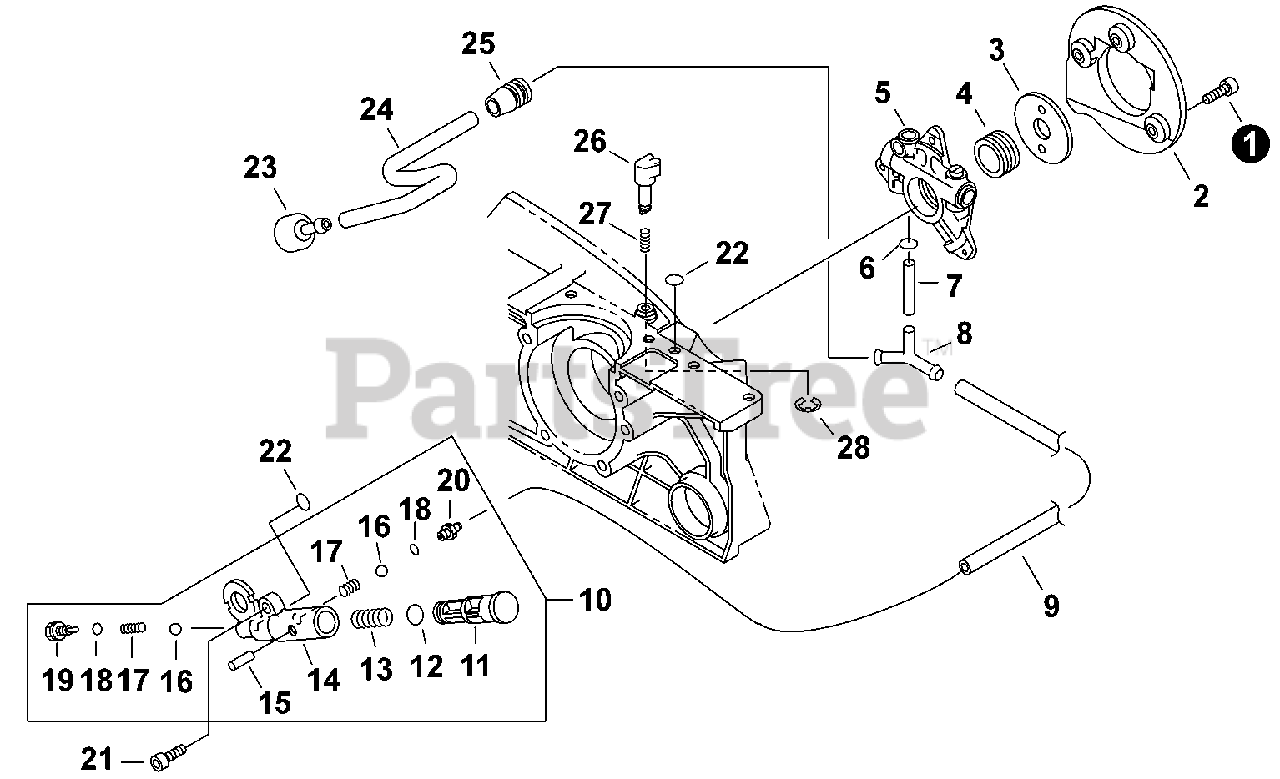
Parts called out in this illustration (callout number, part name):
1	BOLT 4×14
2	COVER, OIL PUMP - ORANGE
4	GEAR, WORM
5	AUTO-OILER ASSY
6	CLIP Ø6.5 MM
7	PIPE, OIL 3×6×20
8	CONNECTOR, PIPE
9	PIPE, FUEL 3×6×210 BLACK
10	OIL PUMP ASSY - BLACK
11	PISTON, OIL PUMP - BLACK
12	O-RING 7 MM
14	BODY, OIL PUMP
15	PIN, SPRING 2×16
16	VALVE, BALL
17	SPRING, COMPRESSION
19	ADAPTOR, OIL PUMP
20	CONNECTOR, PIPE
21	BOLT 5×20
22	O-RING 3
23	FILTER, OIL
24	PIPE, OIL
26	ADJUSTER, AUTO-OILER - ORANGE
28	E-RING 3
